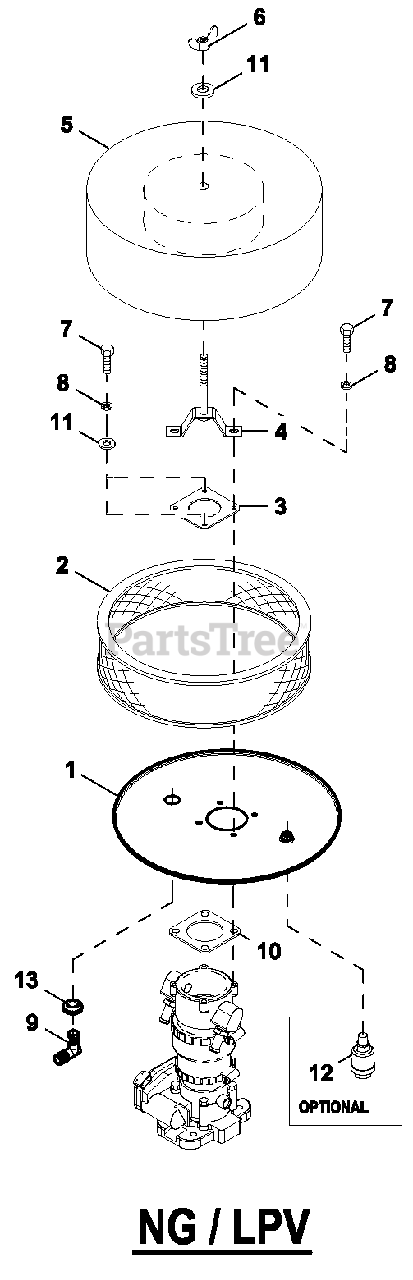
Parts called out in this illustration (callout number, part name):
1	AIR CLNR BTM PLT W/CPLR 8.1 L
2	ELEMENT AIR FILTER
3	TOP PLATE VENTURI
4	HOLD DOWN AIR CLEANER PLATED
5	PLATE AIR CLEAN TOP 5.4L/6.8L
6	NUT WING 1/4-20 NYLK
7	SCREW HHC M6-1.0 X 16 G8.8
8	WASHER LOCK M6-1/4
9	BARBED EL 90 5/8 PLASTIC
10	GASKET MIXER BODY
11	WASHER FLAT 1/4-M6 ZINC
12	INDICATOR FILTER MINDER (USE WITH ITEM #1 P/N 0D2513E)
13	GROMMET .625 X 1.25 X .433
